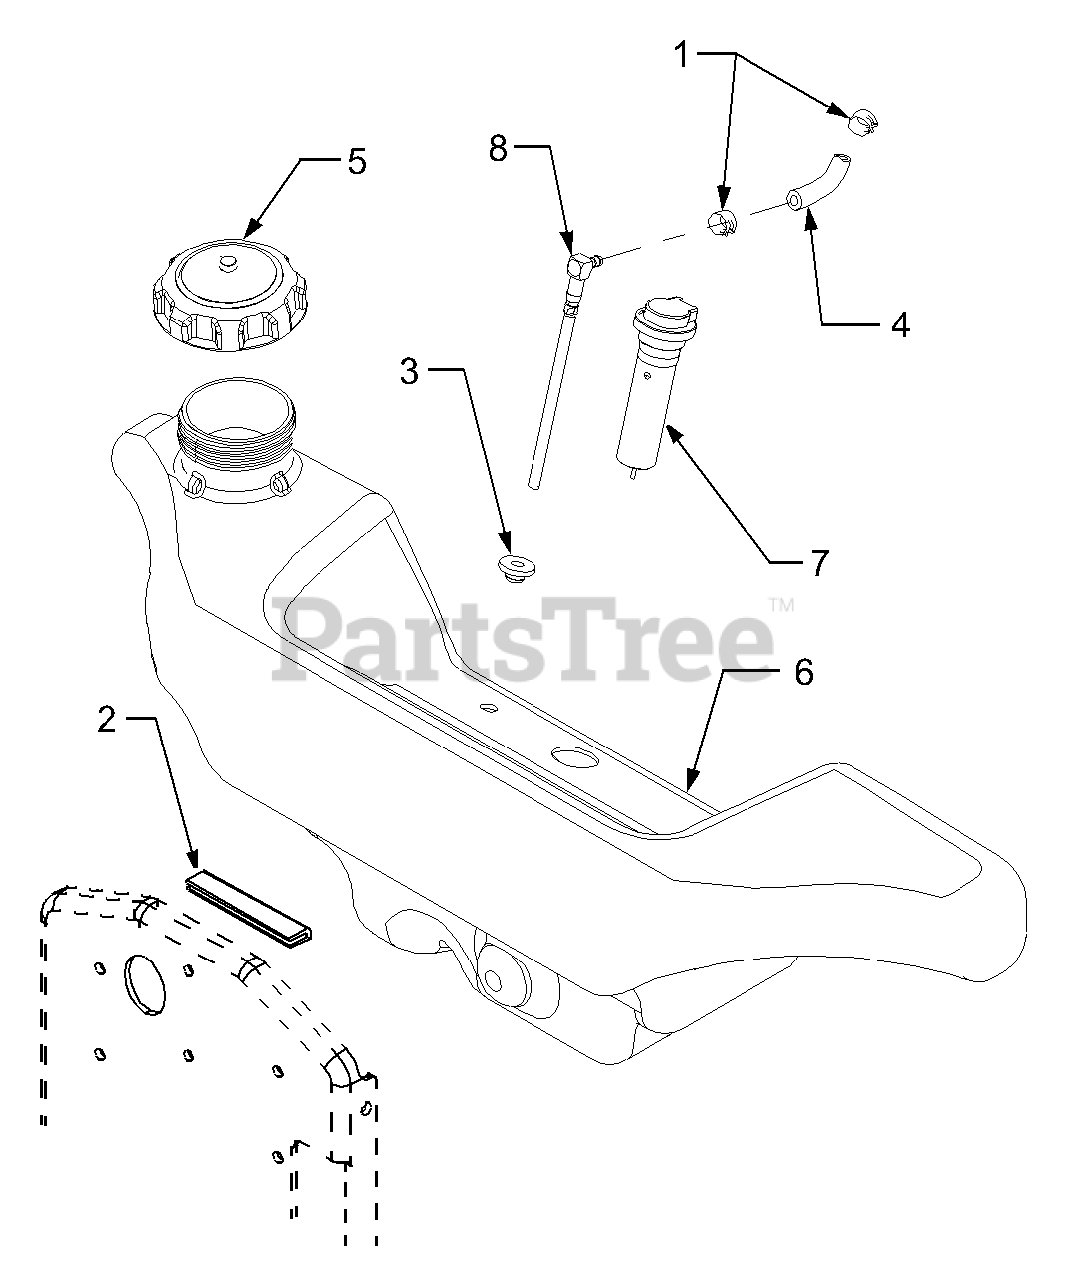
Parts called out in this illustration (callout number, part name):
1	Clamp, Hose
2	Trim, Tank Protector
3	Bushing, Rubber
4	Fuel Line
5	Cap, Fuel
6	Tank, Fuel, 4.5 Gallon
7	Sensor, Low Fuel
8	Fitting, Fuel Pickup
